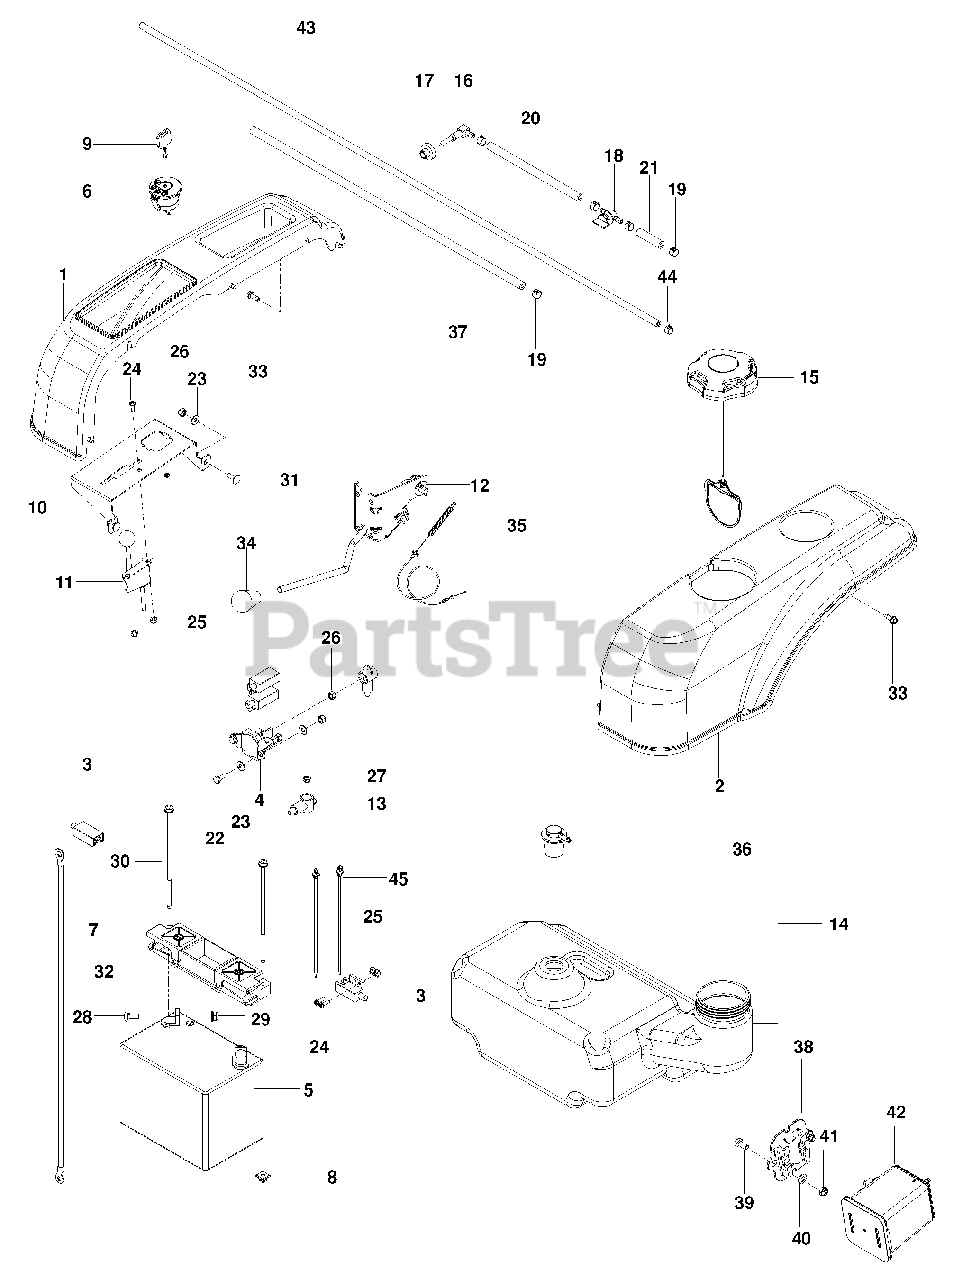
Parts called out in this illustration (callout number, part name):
1	FENDER, RH
2	FENDER, LH
5	BATTERY
6	SWITCH, IGNITION
7	BATTERY HOLD DOWN
8	NUT 1/4 PUSH NYLON
9	KEY, IGNITION
10	PANEL, CONTROL
11	CABLE, THROTTLE
12	CLUTCH ASSY w/ CABLE
13	TERMINAL COVER, SM
14	TANK ASSY, FUEL
15	CAP, FUEL w/ TETHER
16	ELBOW w/ FILTER
17	FITTING, TANK
18	VALVE, FUEL
19	CLAMP, HOSE
20	HOSE 1/4 x 8
21	HOSE, 1/4 x 2
22	HCS 1/4-20 x 3/4
23	WASHER 1/4 FLAT SAE
24	SCREW #10-24 x 5/8
25	NUT #10-24 HEX NYLOC
26	NUT 1/4-20 HEX NYLOC
27	NUT 1/4-20 HEX THIN NYLOC
28	RHSNB 5/16-18 x 3/4
29	NUT 5/16-18 FLANGE NYLOC
30	BOLT 1/4 x 7 1/2
31	RHSNB 1/4-20 x 3/4 GR2
32	BATTERY CABLE, NEGATIVE
33	SCREW 1/4-20 x 5/8 SLF TAP
34	KNOB, CLUTCH
35	CABLE, CLUTCH
36	VALVE, ROLLOVER
37	FUEL LINE 24"
38	BRACKET, CANISTER
39	HCS 5/16-18 x 5/8
40	WASHER 5/16 SAE FLAT
41	NUT 5/16-18 HEX NYL INSERT
42	CANISTER, CARBON
43	FUEL LINE 46"
44	CLAMP, HOSE
